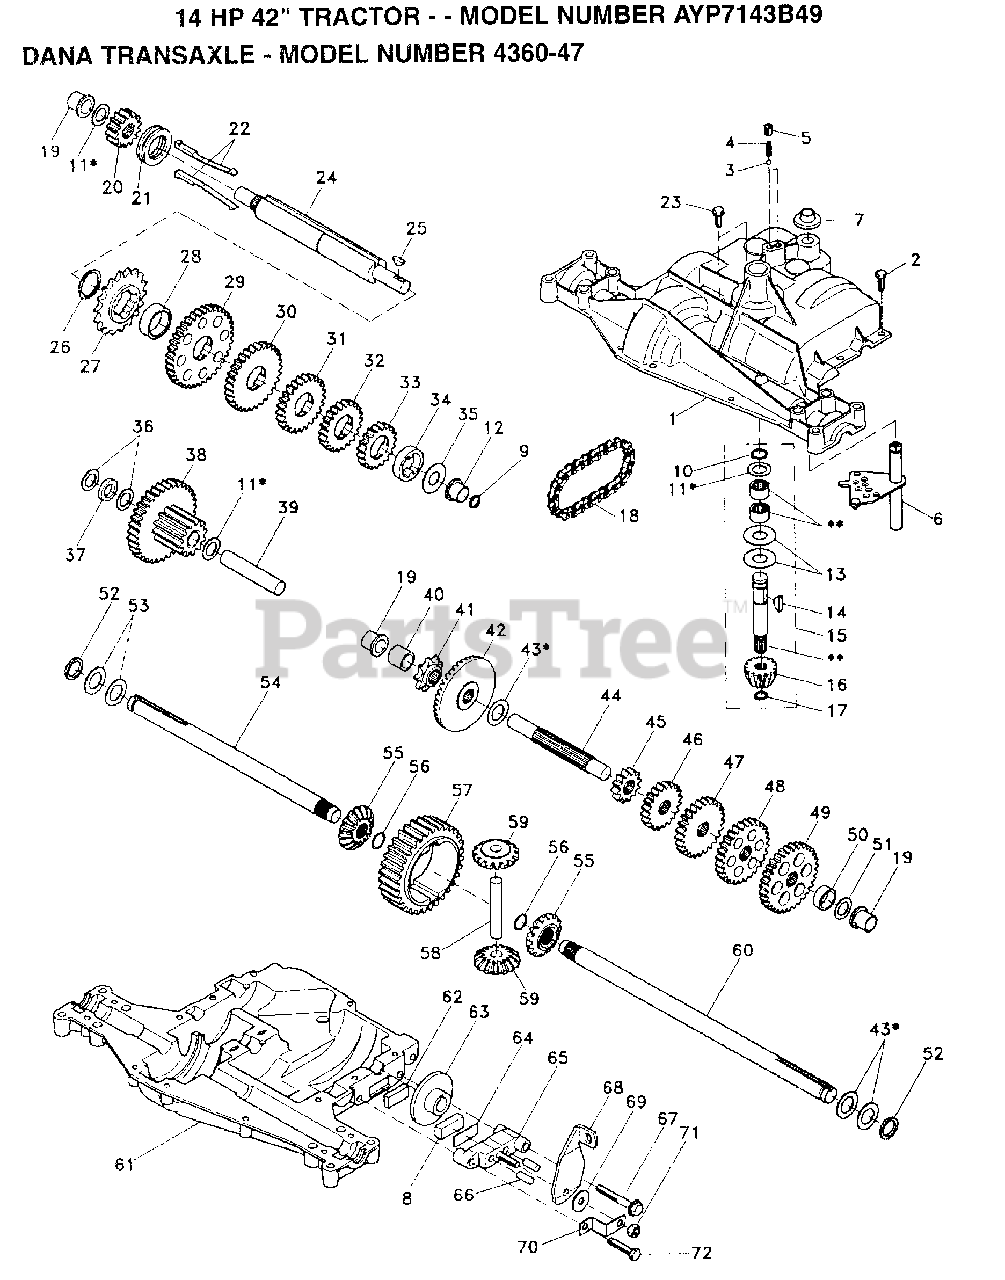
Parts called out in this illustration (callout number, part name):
1	HOUSING UPPER
3	BALL, DETENT
4	SPRING, DETENT
5	SCREW, SET
6	KIT, SHIFTER ASSEMBLY
7	BOOT, SHIFTER
8	PUCK, FRICTION
9	SCREW TAPPING WITH SEALER
10	RING RETAINING
11	ASSY, KIT, SHIM .625 SHAFT
12	GEAR SPUR, 15 TEETH
13	WASHER, PLAIN .632 X 1.38 X .046
14	KEY WOODRUFF #9
15	ASSY KIT INPUT SHAFT
16	PINION BEVEL 14 TEETH
17	RING, RETAINING
18	CHAIN, 24 PITCHES
19	BEARING, FLANGE
20	GEAR SPUR, 14 TEETH
21	COLLAR CLUTCH
22	KEY CLUTCH
23	KEY WOODRUFF #3
24	SHAFT INTERMEDIATE
25	KEY, WOODRUFF, #61
26	RING, RETAINING
27	SPROCKET, 18 TEETH
29	GEAR, SPUR, 37 TEETH
30	GEAR, SPUR, 35 TEETH
31	GEAR, SPUR, 30 TEETH
32	GEAR, SPUR, 25 TEETH
33	GEAR, SPUR, 22 TEETH
34	GEAR, SPUR, 19 TEETH
35	WASHER, PLAIN .640 X 1.37 X .061
36	WASHER, PLAIN .632 X 1.00 X .026
37	SPACER .630 X 1.00 X .169
38	ASSY GEAR COMB 12&35 TEETH
39	SHAFT, IDLER
40	SPACER .635 X .875 X .755
41	SPROCKET, 9 TEETH
42	GEAR, BEVEL, 42 TEETH
43	ASSY, KIT, SHIM .750 SHAFT
44	SHAFT, DRIVE
45	SCREW TAPPING
46	GEAR, SPUR, 12 TEETH
47	GEAR, SPUR, 20 TEETH
48	GEAR, SPUR, 25 TEETH
49	GEAR, SPUR, 28 TEETH
50	GEAR, SPUR, 31 TEETH
51	WASHER, PLAIN .632 X 1.00 X .060
52	WASHER, NEOPRENE
53	WASHER, PLAIN .758 X 1.25 X .031
54	AXLE LEFT HAND
55	GEAR MITER 15 TEETH
56	RING, RETAINING
57	GEAR, SPUR, 32 TEETH
58	SHAFT, CROSS
59	GEAR, MITER, 15 TEETH
60	AXLE, R.H.
61	HOUSING LOWER
62	PUCK, FRICTION
63	DISC, BRAKE
65	JAW, BRAKE
66	PIN, DOWEL
67	SCREW, SELF-TAPPING
68	LEVER, ACTUATING
69	WASHER, PLAIN .321 X 1.00 X .055
70	BRACKET, ANTI-ROTATION
71	LOCKNUT 5/16-24
